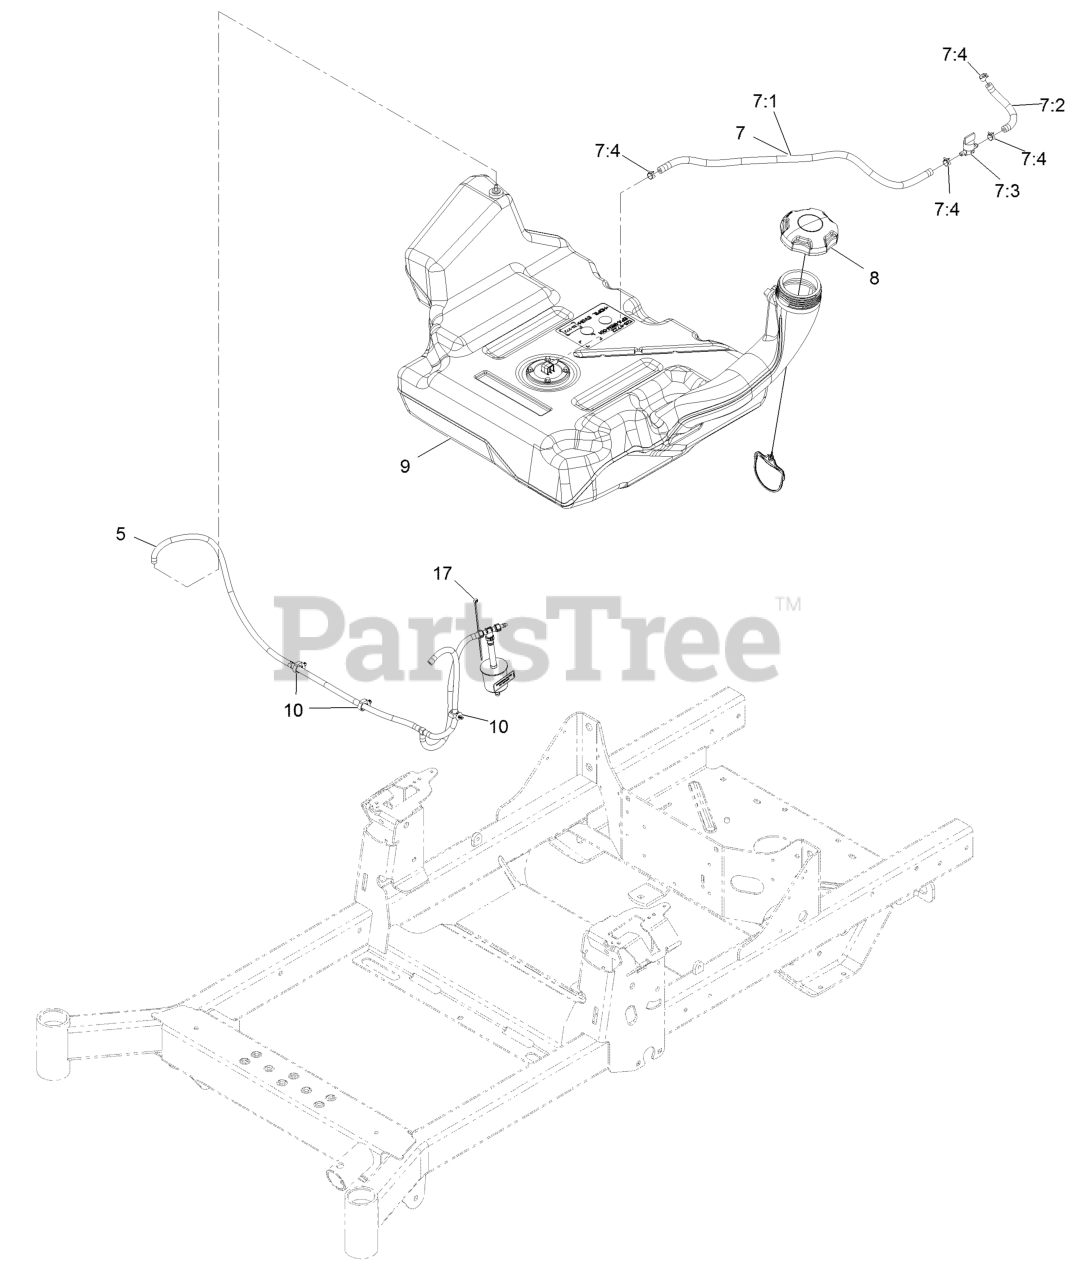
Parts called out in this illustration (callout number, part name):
5	Vent Hose ASM
7	Fuel Hose ASM
7:1	Hose-Fuel Line 24"
7:2	Hose-Fuel
7:3	Valve-Fuel
7:4	Clamp-Hose
8	Cap-Fuel
9	Fuel Tank ASM
17	Tie-Cable 5 1/2 (Small)
